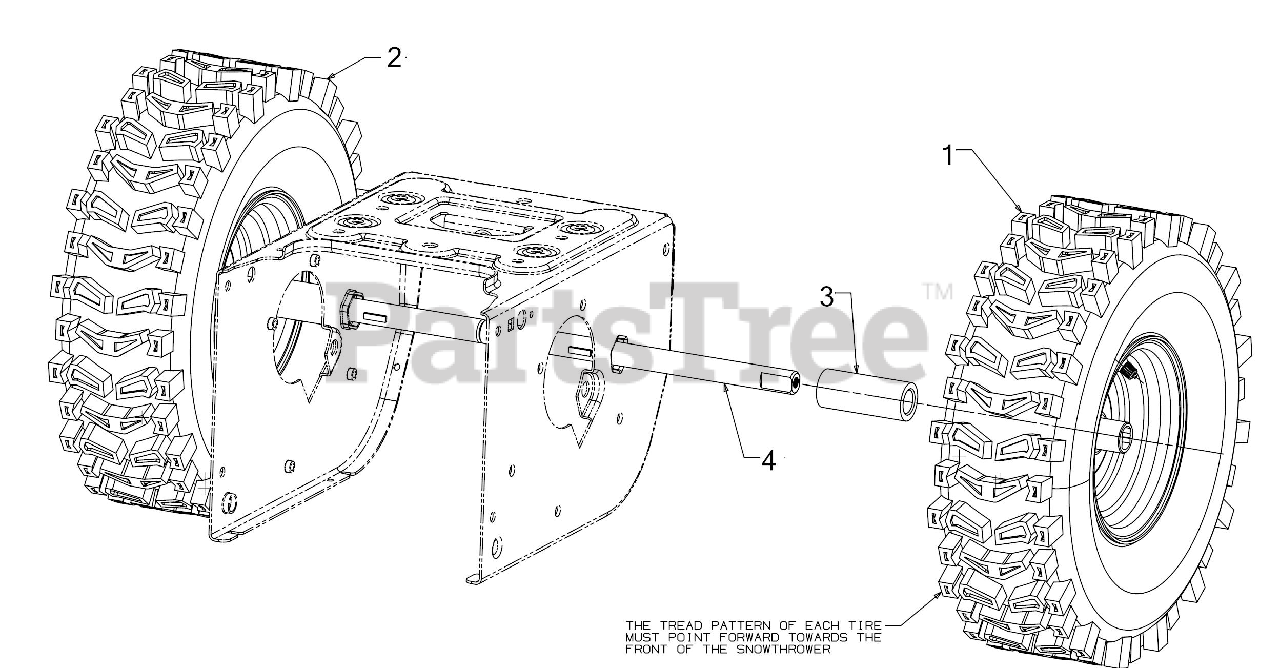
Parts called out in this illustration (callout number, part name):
1	WHEEL ASSEMBLY (15 x 5 x 6) (LH)
2	WHEEL ASSEMBLY (15 x 5 x 6) (RH)
3	WHEEL SPACER 1.25ODX.75X3.00
4	AXLE .75OD x 11.12LG
